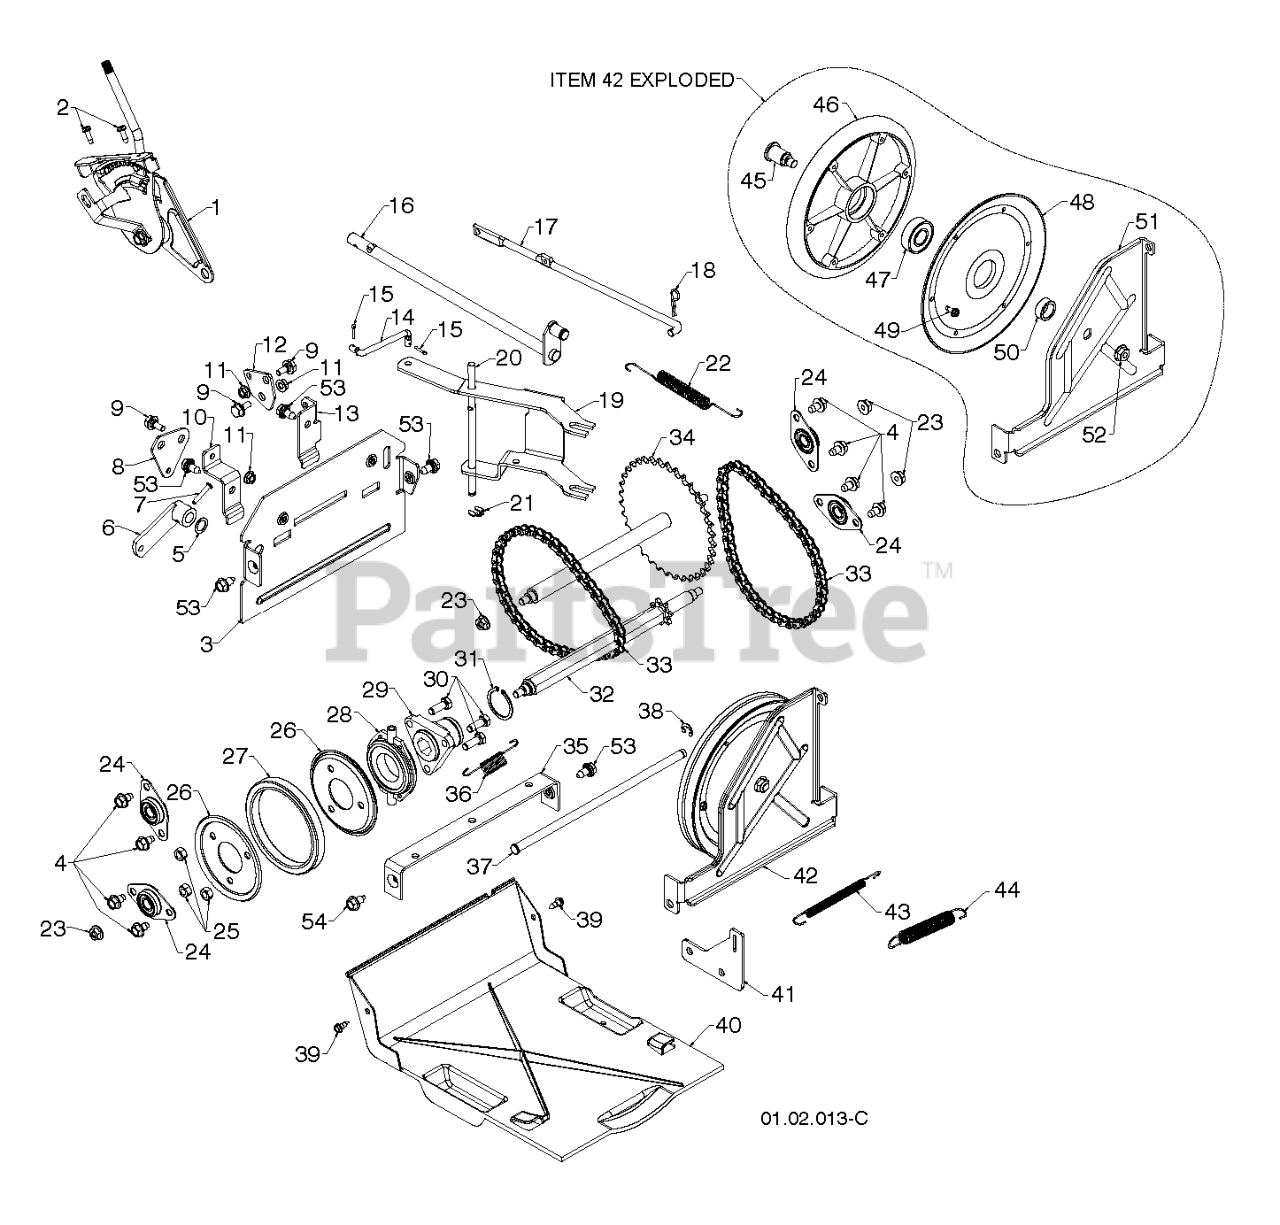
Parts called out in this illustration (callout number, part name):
1	HEAD ASSY SPEED
2	SCREW #10-24 X 5/8
3	PLATE.END.CHAIN.ASM.PNT.ORANGE
4	Screw 5/16-18 x 1/2 Hex, Self Tapping 5/16-18 x 1/2
5	THRUST WASHER
6	ARM, AUGER CONTROL
7	CLEVIS PIN
8	PLATE.SHIFTER.BZP
9	BOLT.SHOULDER.3/X.25
10	BRACKET.SHIFTER.PLATE.BZP
11	NUT.HEX.FLANGE.1/4
12	PLATE.CLUTCH.BZP
13	BRACKET.CLUTCH.PLATE.BZP
14	LINK, SPEED CONTROL
15	RETAINER CLIP
16	CONTROL.SHAFT.ASM
17	ROD.CLUTCH.SWING.PLATE
18	SPRING RETAINER
19	BRACKET.YOKE.SHIFTER.BLACK
20	ROD.PIVOT.SHIFTER
21	KLIP RING TI
22	SPRING.TRACTION.RETURN
23	NUT.LOCK.5/16-18
24	BEARING FLANGE BALL
25	NUT.CENTERLOCK.5/16-
26	PLATE.RUBBER.WHEEL
27	RING.RUBBER.2-STG.SNW.DRV.WH
28	TRUNNION BEARING ASSY
29	HUB, RUBBER WHEEL
30	BOLT
31	RETAINING RING (2 2)(3 2)
32	SHAFT.HEX.W/SPOCKET
33	CHAIN.DRIVE.SNOWTHROWER.#420
34	SPROCKET.WELDMENT
35	SHIFTER BRACKET
36	SPRING, BIAS
37	ROD.PIVOT.SWING.PLATE.SNOW
38	E-RING.RETAINER.REINFORCED.375
39	SCREW, HEX HEAD, TAPPING
40	PAN.BOTTOM.PLASTIC
41	BRACKET.TRACTION.SPRING.
42	RP.PULLEY.PLATE.ASM.DRIVE
43	SPRING.TRACTION.IDLER
44	SPRING, BRAKE
45	SHAFT.FRICTION.PULLEY.SNOW
46	PULLEY.PLATE.ASM.DRIVE
48	RP PULLEY.HALF.TRACTION
50	SPACER BEARING
51	PLATE.SWING.DRIVE.BLACK
52	FLANGED LOCKNUT 3/8-16 ZINC
53	BOLT.HEX.HD.WASHER.5/16-18X.75
54	BOLT.5/16HEX.WHS.HD
